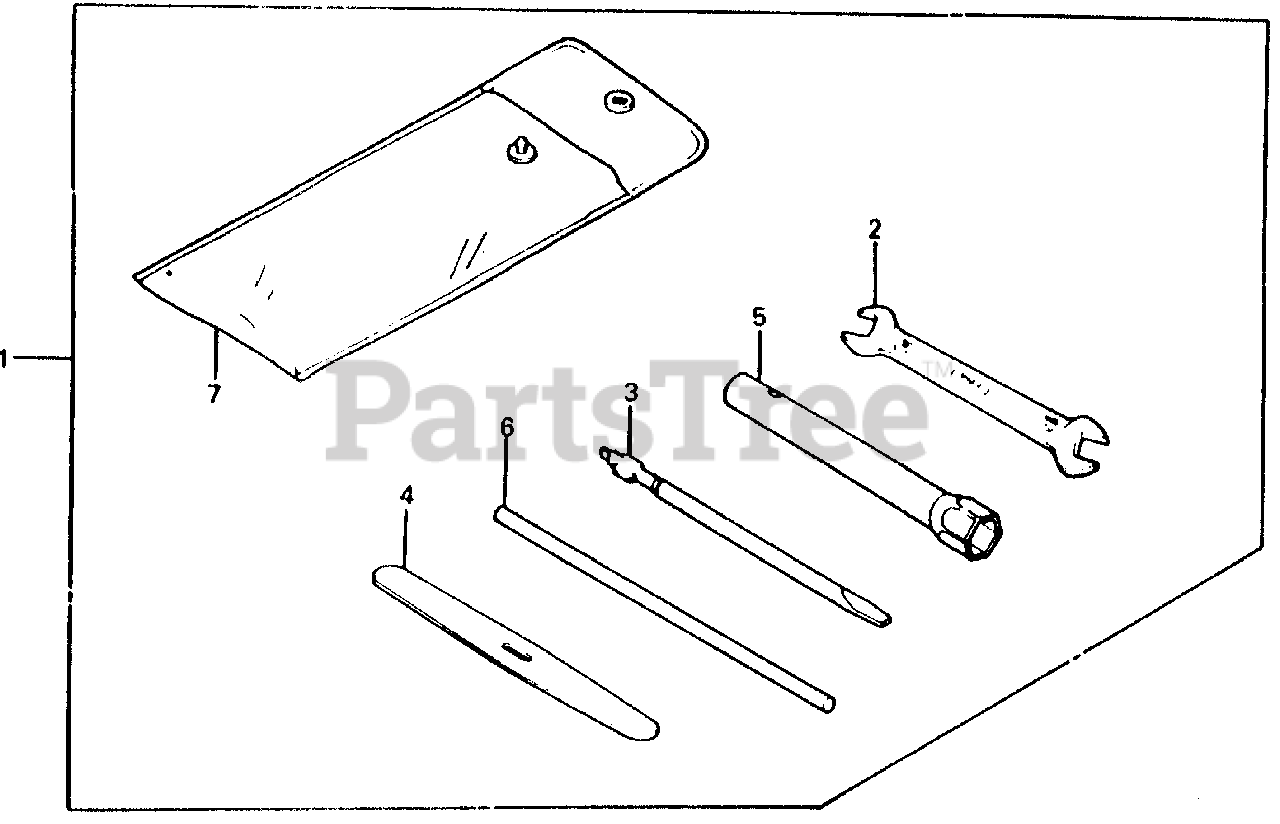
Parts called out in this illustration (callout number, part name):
2	WRENCH (10X12) (OPEN END)
3	SCREWDRIVER 3, STRAIGHT SLOT (NO.2)
4	LEVER, TIRE
5	WRENCH, BOX (P21)
6	BAR A, HANDLE
